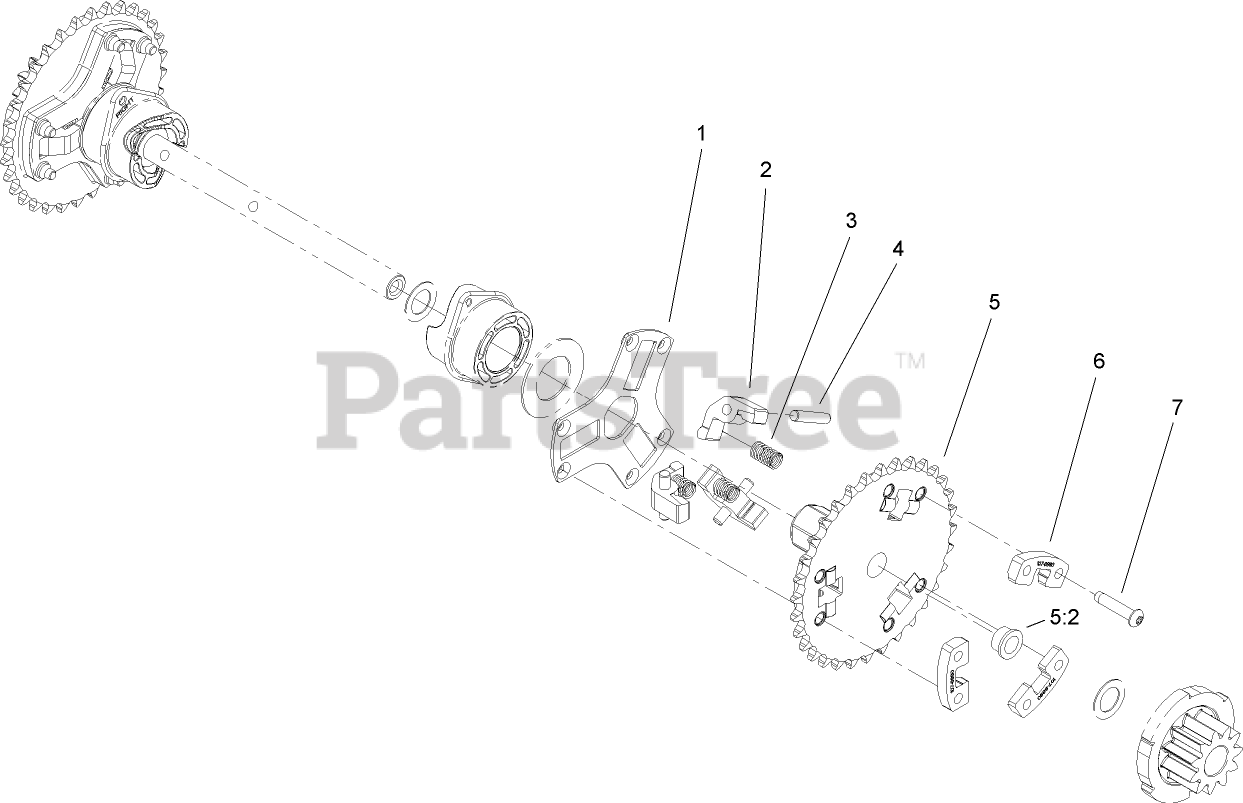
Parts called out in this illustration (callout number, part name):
1	RETAINER-PIN, PAWL
2	PAWL-CLUTCH
3	SPRING-COMPRESSION
4	PIN-DOWEL
5	32T SPROCKET ASM
5:2	BUSHING-FLANGE
6	SUPPORT-PAWL
7	SCREW-TTH, THREAD ROLLING
